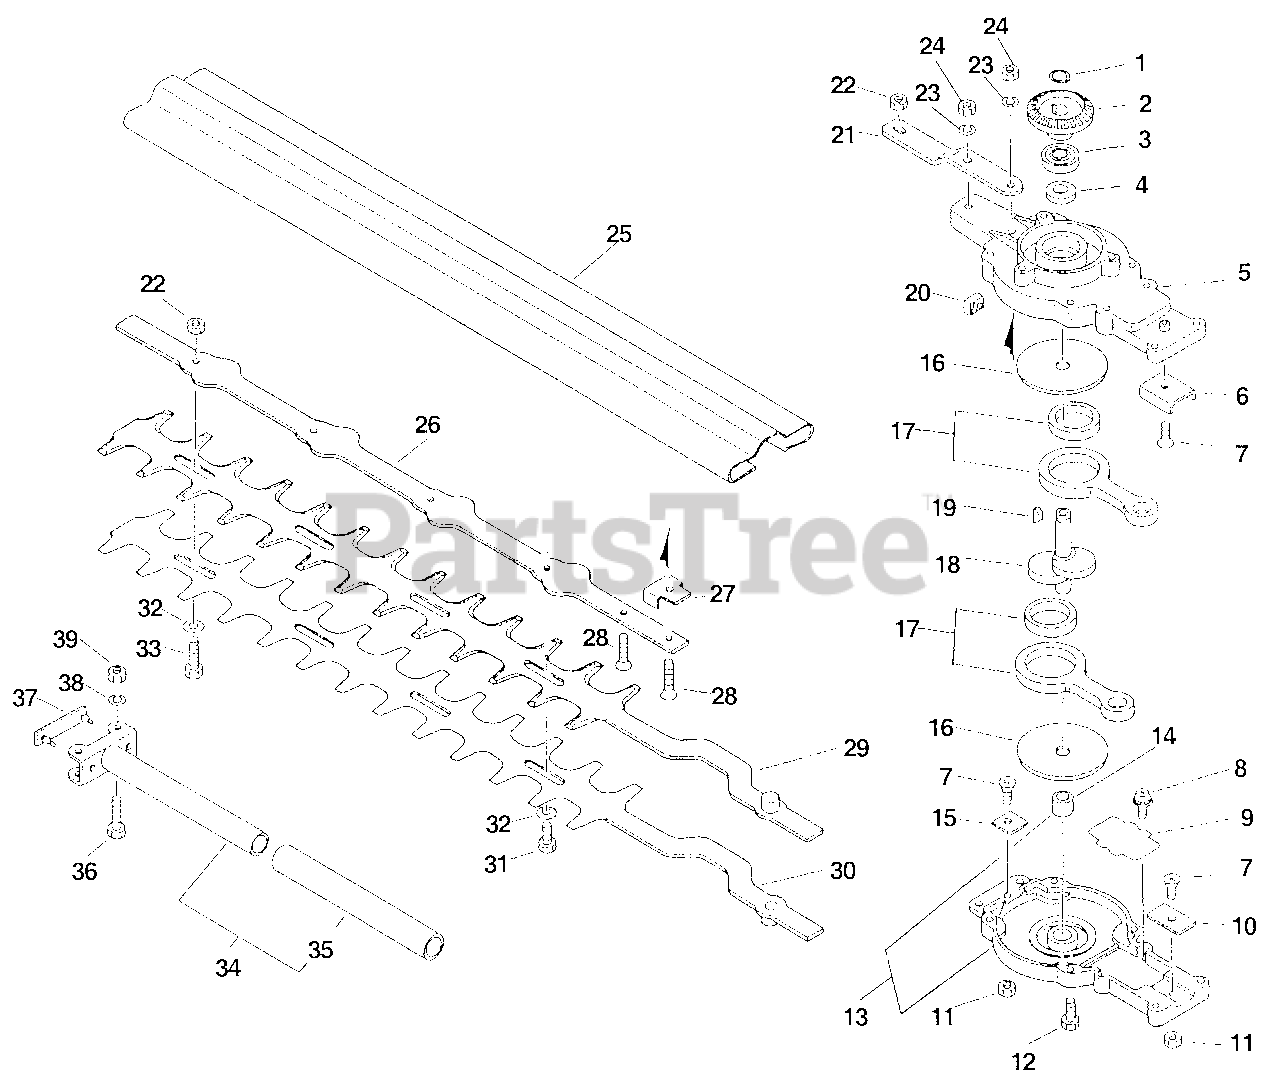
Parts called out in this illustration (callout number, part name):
1	E-RING 10
2	GEAR, SPUR
3	BEARING, BALL 6000
4	SEAL, OIL
5	GEARCASE
7	SCREW 4×8
8	SCREW 3×6
9	PLATE, SIDE
10	PLATE, EYE
12	BOLT 5×20
13	BEARING, PLAIN
14	BEARING, PLAIN
15	PLATE, GUIDE
16	PLATE, SIDE
17	CONROD ASSY
21	SUPPORT, CUTTER
23	WASHER, SPRING 5
25	SCABBARD, BLADE
26	GUIDE BAR
27	PLATE, ANGLE
28	SCREW 5×20
29	CUTTER, UPPER
30	CUTTER, LOWER
31	BOLT, CUTTER
32	WASHER 6.5×15.5×0.6
33	BOLT, CUTTER
34	ADJUSTOR ASSY, HANDLE
35	GRIP, HANDLE
36	BOLT, 5X25
37	EYE PLATE
38	WASHER, SPRING 5
